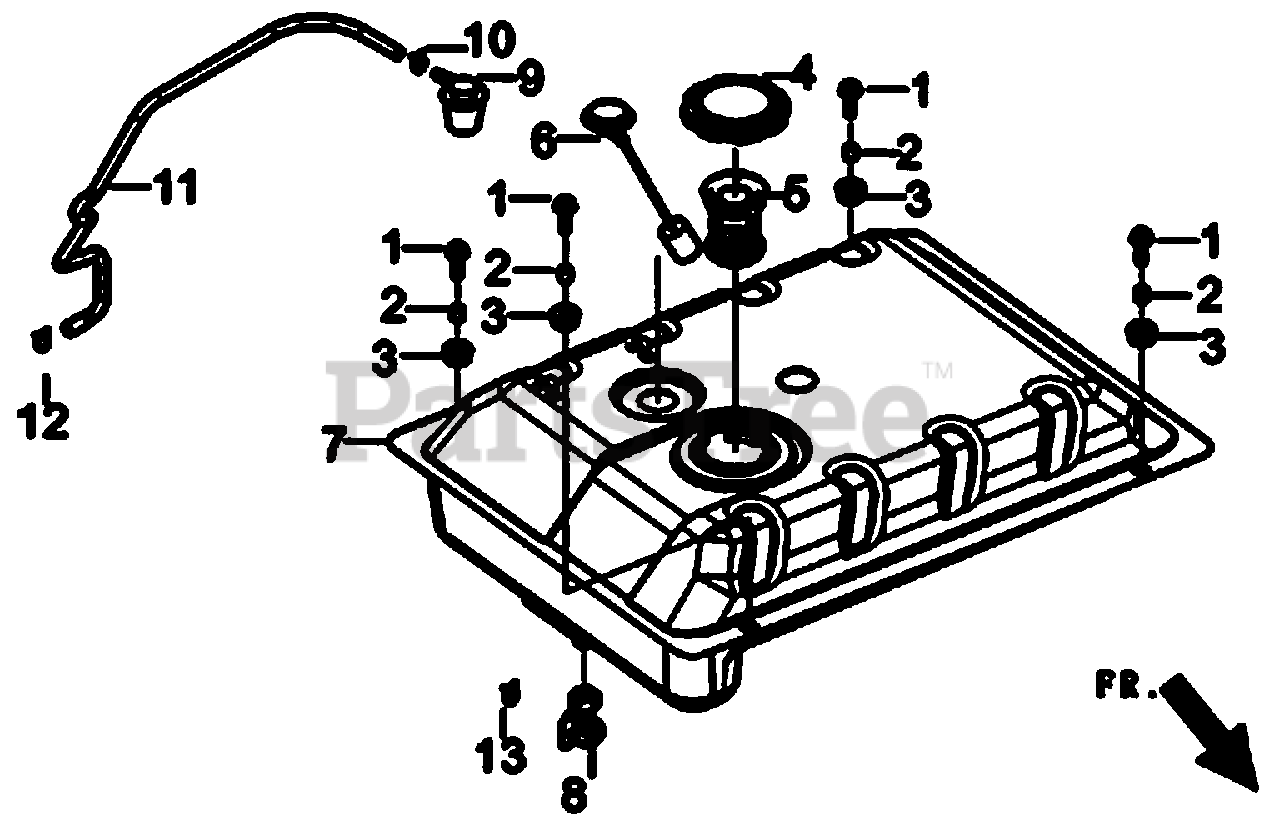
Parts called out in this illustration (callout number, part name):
2	ANTI-CRUSH 10.8OD 9ID 10LG
3	RUBBER MOUNT,10.3 ID X 11 HGT
4	FUEL CAP VENTED
5	FILTER, FUEL
6	FUEL GAUGE 130LG
7	TANK, FUEL
8	VALVE FUEL SHUTOFF
9	ASSEMBLY ROV
13	CLAMP HOSE BAND SPRING .38
